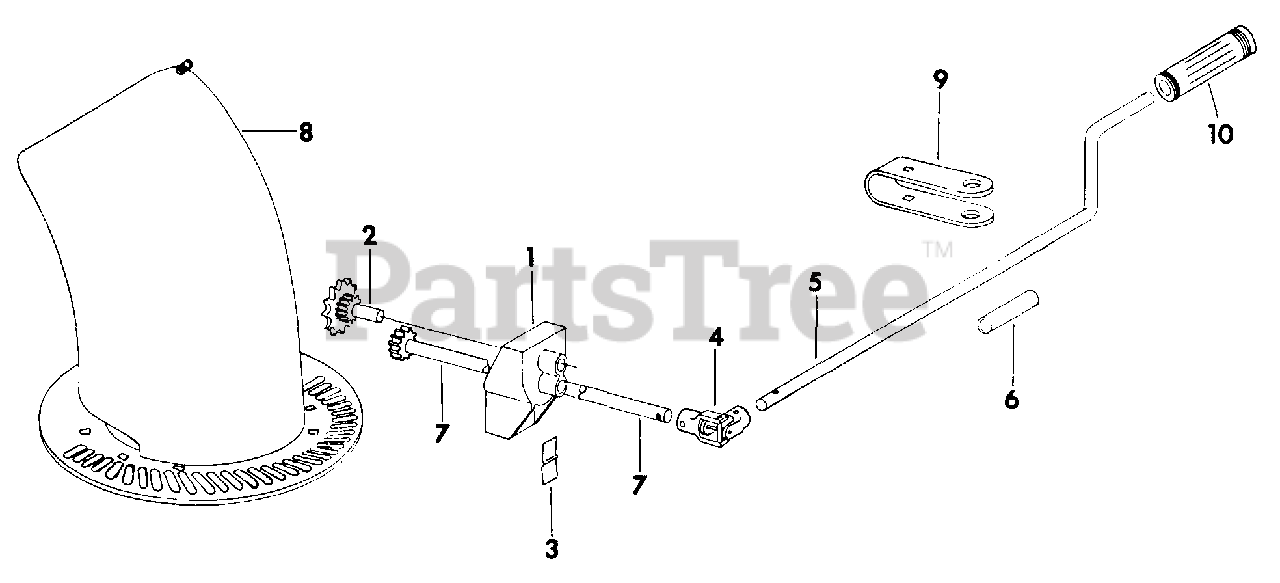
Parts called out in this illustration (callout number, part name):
1	SUPPORT, SPROCKET BEARING
2	SPROCKET ASSY
4	UNIVERSAL JOINT
5	HANDLE, CHUTE CONTROL
6	SLEEVE, CONTROL HANDLE
7	GEAR ASSY, DRIVE
8	CHUTE, SNOW
9	BRACKET, CHUTE CONTROL
10	GRIP, CHUTE CONTROL HANDLE
